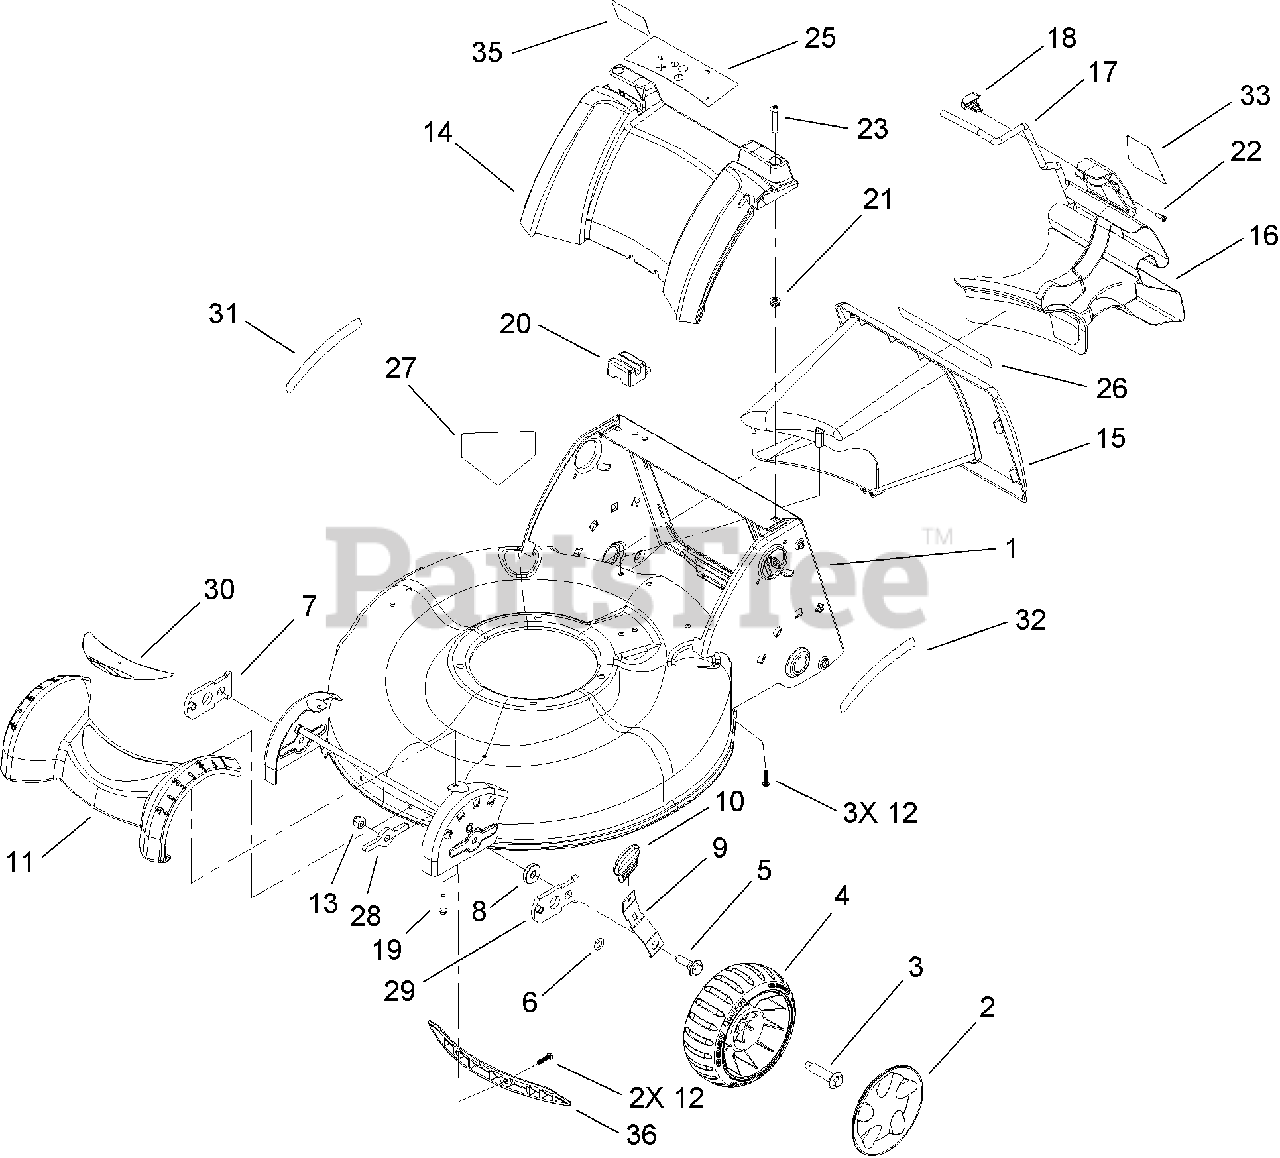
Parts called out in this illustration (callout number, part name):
1	HOUSING ASM
2	COVER-WHEEL, 7 INCH
3	BOLT-SHOULDER
4	7 INCH WHEEL ASM
5	BOLT-SHOULDER
7	ARM-PIVOT, RH
9	ARM-SPRING
10	KNOB-LEVER, HOC
11	COVER-FRONT
12	SCREW-PLASTITE
13	NUT-LOCK, NI
14	COVER-REAR
15	TUNNEL
16	PLUG-CHUTE
17	LATCH-PLUG
18	RETAINER-LATCH
19	SCREW-PLASTITE
20	MODULE-SWITCH
21	NUT-CLIP
22	SCREW-PPH
23	SCREW-PTH
25	DECAL-WARNING
26	DECAL-SAFETY
27	DECAL-DANGER
28	WASHER-SUPPORT, FRONT
29	ARM-PIVOT, LH
31	DECAL-HOC, RH
32	DECAL-HOC, LH
33	DECAL-MULCH PLUG, CE
35	DECAL-BAG ATTACHMENT, CE
36	INSERT-HOUSING
